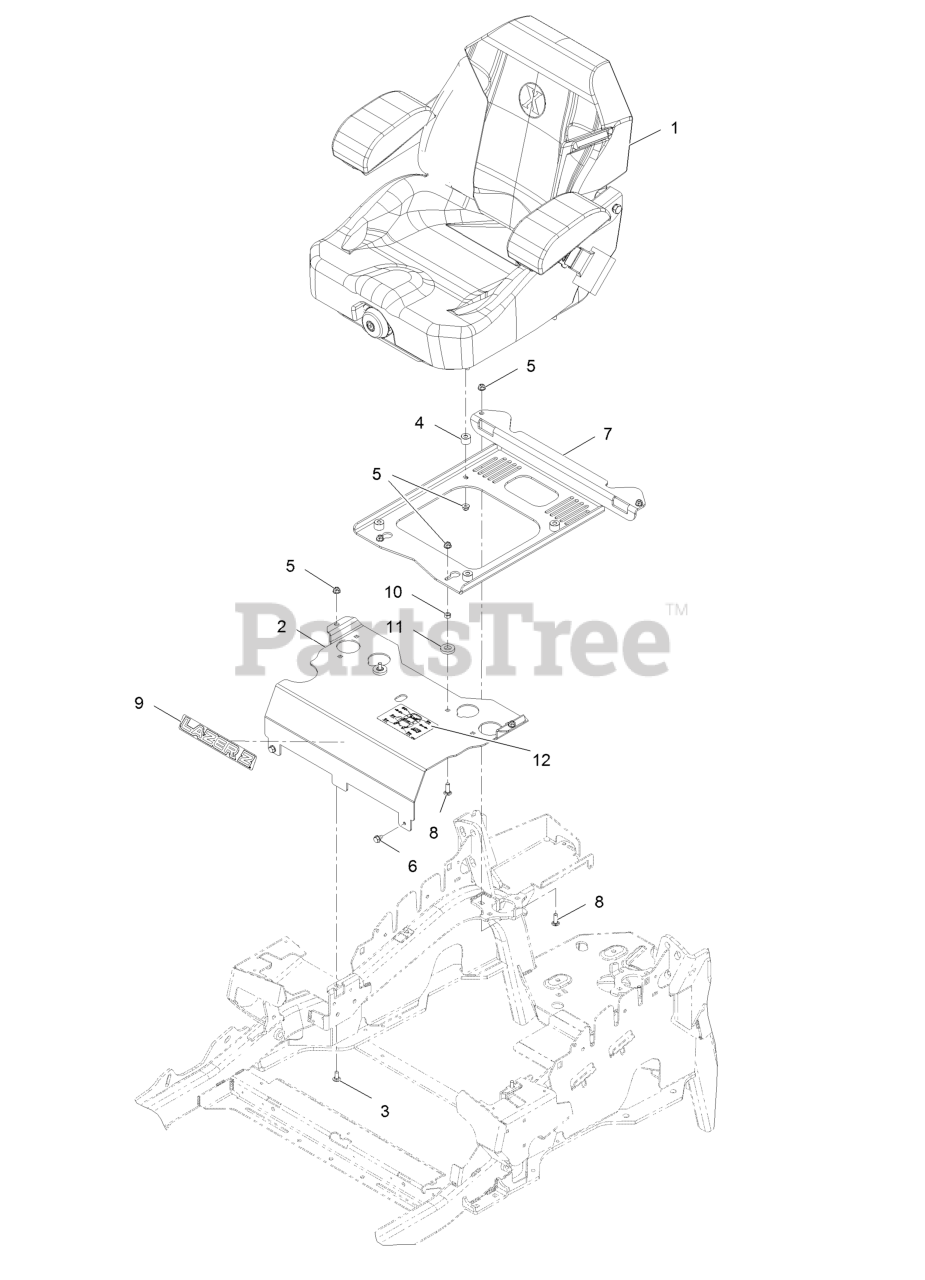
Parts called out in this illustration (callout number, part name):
1	Kit-Suspension Seat
2	Panel-Front, Seat Mount
3	Bolt-Carriage 5/16-18 X 3/4 Short Neck
5	Nut-Nyloc 5/16-18 Flg
6	Screw-HWH 5/16 X 1/2 Tf
7	Plate-Support, Seat
8	Bolt-Carriage 5/16-18 X 1 Sp
9	Decal, Lazer Model
10	Nut-Hex 5/16-18
11	Spacer-Blade Drive
12	Decal-Service Aid
